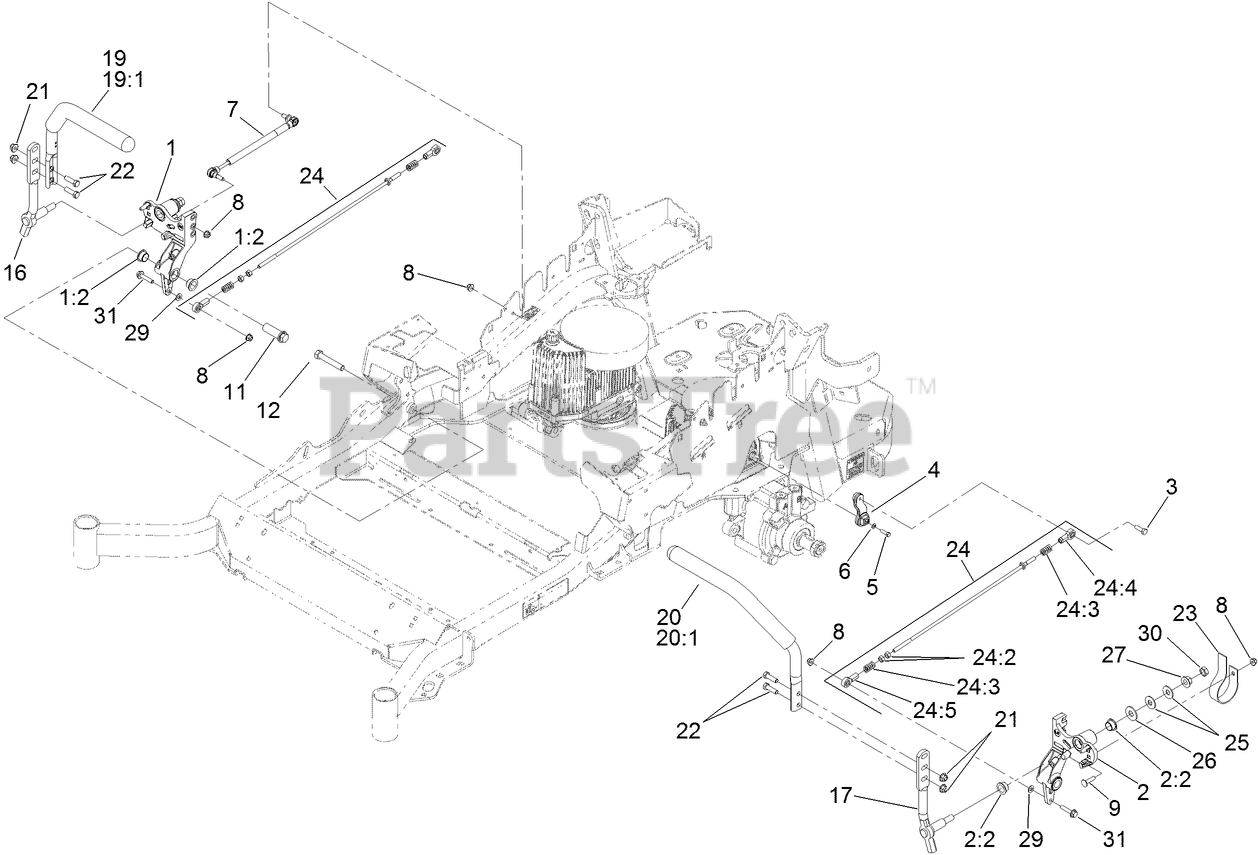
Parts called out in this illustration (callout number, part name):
1	RH MOTION CONTROL AND BUSHING ASM
1:2	BUSHING-FLANGE
2	LH MOTION CONTROL AND BUSHING ASM
2:2	BUSHING-FLANGE
3	SCREW-HH, THREAD LOCKING
4	ARM-CONTROL, PUMP
5	SCREW-HH
6	WASHER-SPRING
7	DAMPER-CONTROL, MOTION
8	NUT-HF, NI
9	BOLT-CARR
11	HUB-THREADED
12	SCREW-HH
16	LEVER-CONTROL MOTION, RH
17	LEVER-CONTROL MOTION, LH
19	RH STEERING HANDLE ASM
19:1	Grip-Control, Motion
20	LH STEERING HANDLE ASM
20:1	Grip-Control, Motion
21	NUT-HF, NI
22	SCREW-HH
23	SPRING-LEAF
24	FRONT PUMP LINKAGE ASM
24:2	NUT-HEX
24:3	SPRING-COMPRESSION
24:4	BALLJOINT-LH
24:5	BALLJOINT-RH
25	WASHER-SPRING
26	WASHER-FLAT
27	NUT-HF
29	WASHER-PLAIN
30	NUT-JAM
31	SCREW-HHF
